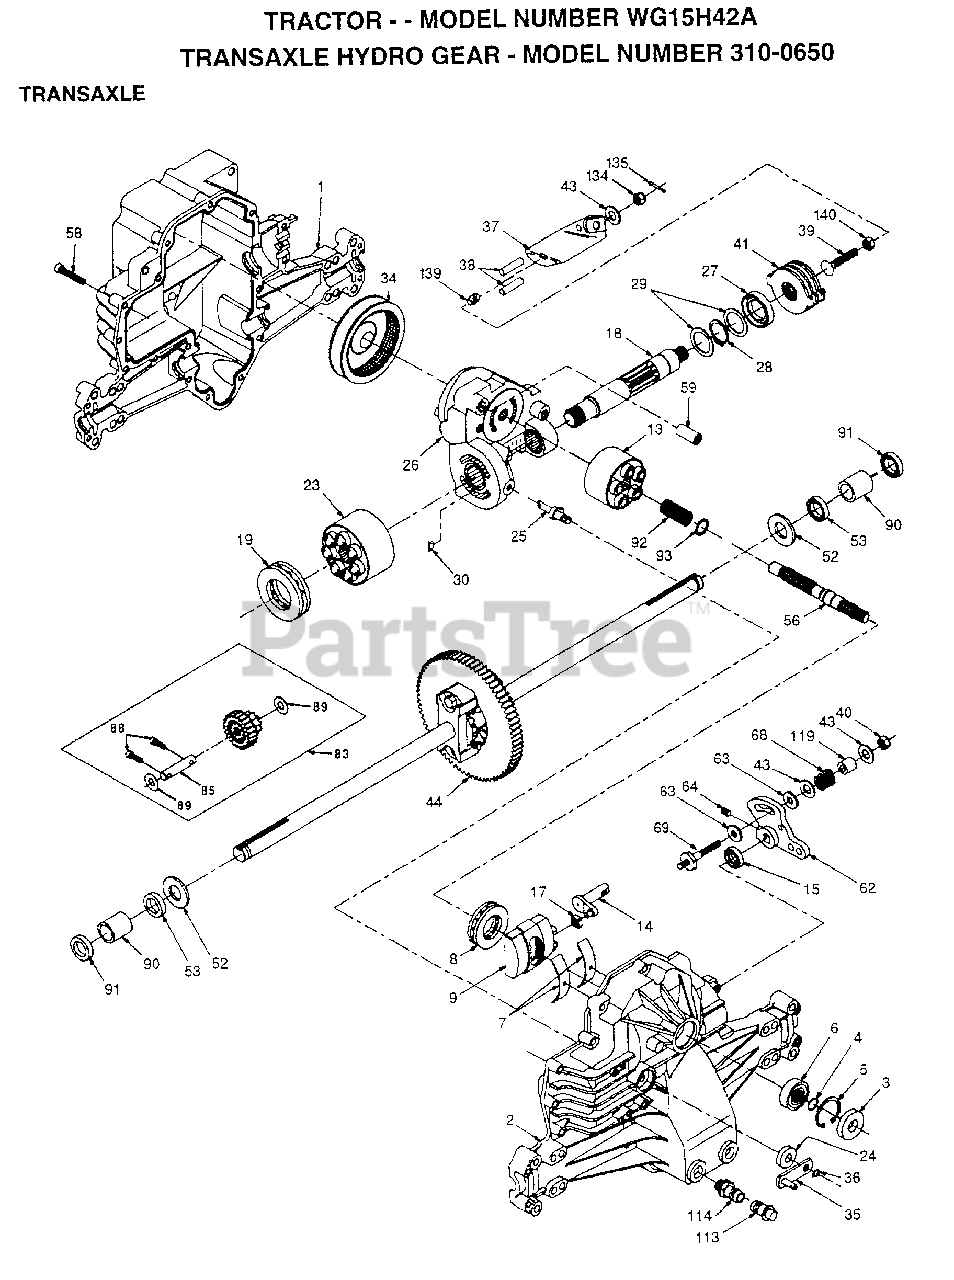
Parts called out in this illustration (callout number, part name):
1	HOUSING.L.50074RM
2	HOUSING.UP.70125
3	SEAL.9008000-0128
4	RING.RET.2003016.
5	RING.RET.2003052.
6	BEARING.(50552)42X68X16
7	CRADLE- 2003023.
8	BEARING.THU.50551
9	SWASHPLT.2003087.
13	BLOCK.CLYN.70079.
14	ARM.TRUN.2003005.
15	SEAL.9008000-0126
17	GUIDE.2000015.
18	SHAFT.MOTOR.50449
19	BEARING.THU.50552
23	BLOCK.CYLIN.70082
24	SEAL.LIP.45074
25	ACTUATOR.2003555
26	KIT.CEN.SEC.70250
27	SEAL.LIP.45075
28	RING RETAIN 50007
29	WASHER.44872
34	ELEMENT.OIL.44964
35	ARM.BYPASS.50270
36	RING.RETAIN.44870
37	ARM.ACTUAT.23710
38	PIN.ACTUAT.44891
39	BOLT.50316
40	NUT.LOCK.HX.50317
41	KIT.BRAKE.70135
43	WASHER HYD 44130
44	DIFFRENTIAL.70226
52	WASHER.HYD.44875
53	SEAL.HYDRO.45076
56	SHAFT.INPUT.50005
58	BOLT.1/4-20.44876
59	PIN.HYDRO.50002
62	ARM.CONTROL.50254
63	PUCK.DAMPER.50281
64	SCREW.SET.50018.
68	SPRING.HYD.50277
69	STUD.5/16-24.DANA
83	JACKSHAFT/PINION GEAR.70132
85	PIN.SHAFT 50559
88	SCREW.CAP.50154.
89	WASHER.HYD.50132
90	BEARING.SLV.50118
91	SEAL.WIPER.50941
92	SPRING.2003014.
93	WASHER.2003017
113	CAP.VENT.70109
114	O-RING.ASM.70110
119	SPACER.HYD.50278
134	NUT.CAS.HYD.44142
135	PIN.COT.HYD.44101
139	SPRING.COMP.50431
140	NUT.HEX.50269
